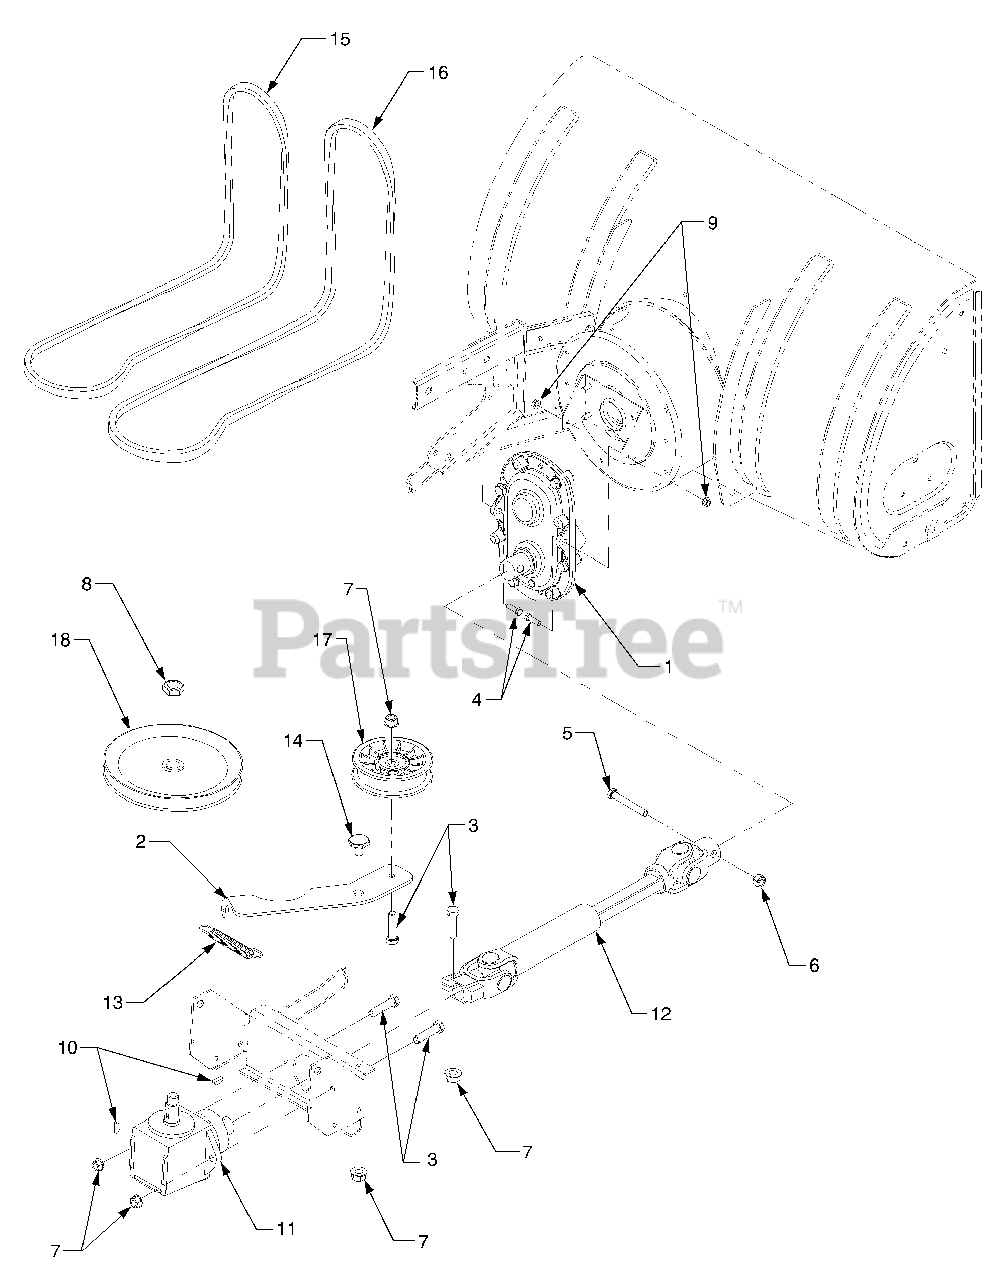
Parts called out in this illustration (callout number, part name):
1	Box Assembly, Sprocket
2	Arm, Idler Pivot
3	Screw, Hex Cap 3/8-16 x 1.5 GR5
4	Screw, Hex Cap 1/4-20 x .75 GR5
5	Screw, Hex Cap 5/16-24 x 2.0 GR5
6	Nut, Hex, 5/16-24
7	Nut, Hex Flange Lock, 3/8-16
8	Nut, Hex Center Lock, 5/8-18
9	Nut, Hex Nylon Insert Lock, 1/4-20
10	Key, Hi-Pro, 3/16 x 3/4
11	Box, Gear
12	Shaft, Drive
13	Spring, Extension
14	Bolt, Shoulder, .625 Dia. x .21
15	Belt, PTO, A-Section x 76.1
16	Belt, PTO, B-Section x 78.3
17	Pulley, Flat Idler
